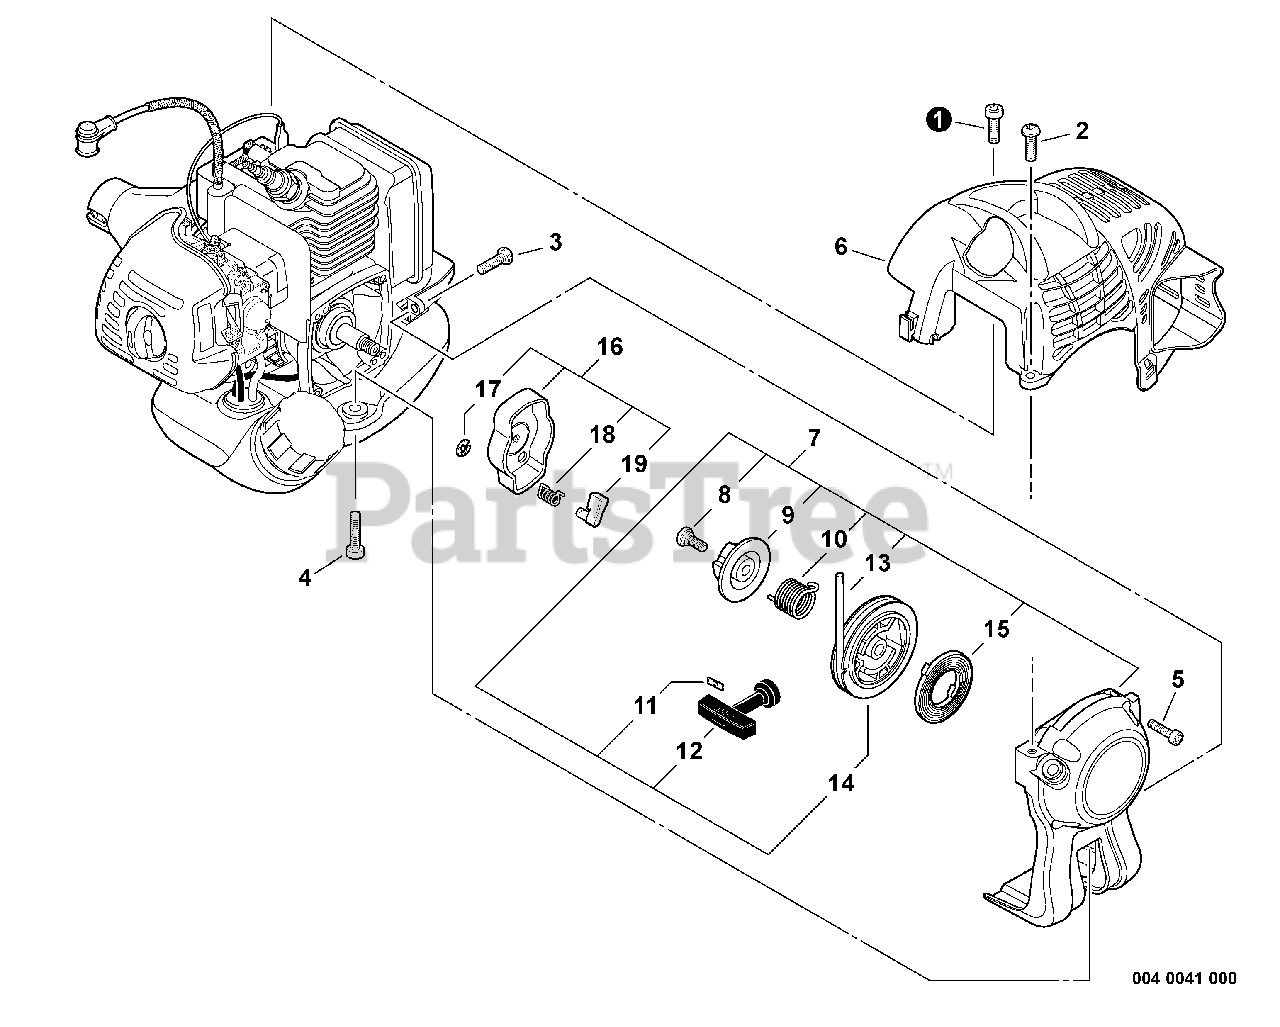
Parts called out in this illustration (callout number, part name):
1	SCREW - 5X16
2	SCREW - 5X16
3	SCREW - 5X16
4	SCREW - 5X20
5	SCREW - 4X16
6	COVER, ENGINE
7	STARTER ASSY
8	SCREW
9	PLATE, CAM
10	SPRING, DAMPER
11	RETAINER, ROPE
12	GRIP, STARTER
13	ROPE, STARTER - 3X700
14	REEL, ROPE
15	SPRING, REWIND
16	STARTER PAWL ASSY
17	RING, RETAINING - 4
18	SPRING, RETURN
19	PAWL, STARTER
